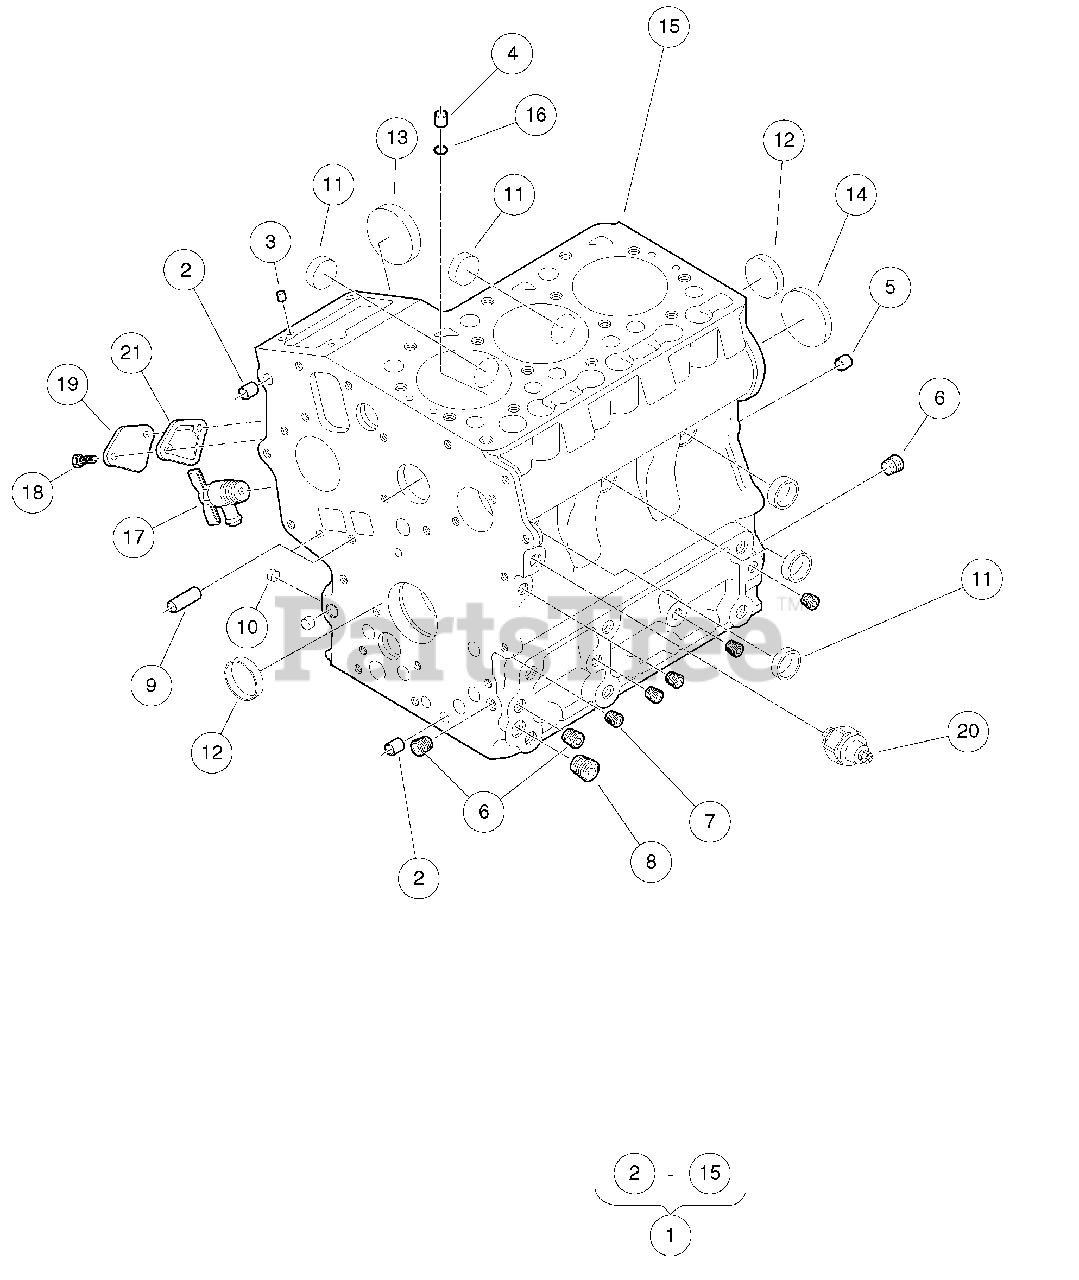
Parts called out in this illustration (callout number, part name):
1	Engine Block
2	Pin, Pipe, Dia 8 X 14
3	Pin, Straight, Dia 5 X 10
4	Pin, Pipe, Dia 7 X 14
5	Pin, Straight, Dia 8 X 16
6	Plug, 1/8"
7	Plug, 3/32"
8	Plug, 1/4"
9	Pin, Pipe, Dia 8 X 11
10	Cap, Sealing, Small
11	Cap, Sealing, Med
12	Cap, Sealing, Large
13	Cover, Fuel Camshaft
14	Plug, Expansion
15	Block, Engine
16	Ring, 8 X 7
17	Cock, Drain
18	Bolt, M6 X 1 X 20
19	Plate, Engine Block
20	Switch, Oil Pressure
21	Gasket, Fuel Pump, D722
